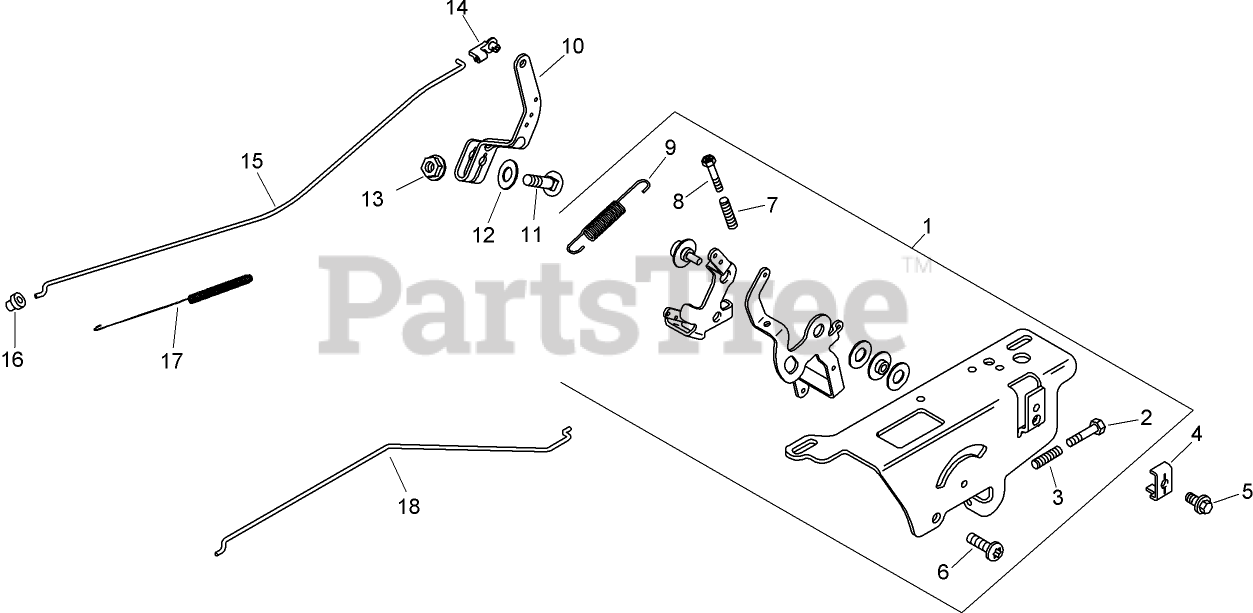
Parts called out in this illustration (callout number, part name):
1	Speed Control ASM
2	Screw-Thread Forming (M4x0.7x25)
3	Spring-Control, Speed
4	CLAMP-CABLE
5	SCREW-FLANGE, THREAD FORMING (M5X0.8X16)
6	Screw-Socket, 6 Lobed (Thread Forming, M6x1.0x20)
7	Spring-Control, Speed
8	Screw-Thread Forming (M4x0.7x25)
9	Spring-Governor
10	Lever-Governor
11	Bolt-Square Neck, Round Head (1/4-20x1)
12	Washer-Lock, Internal Tooth (1/4)
13	Nut-Flange, Hex (1/4-20)
14	BUSHING-RETAINING, LINKAGE
15	Linkage-Throttle
16	BUSHING-LINKAGE, THROTTLE
17	Spring-Linkage
18	Linkage-Choke (Single Wire)
